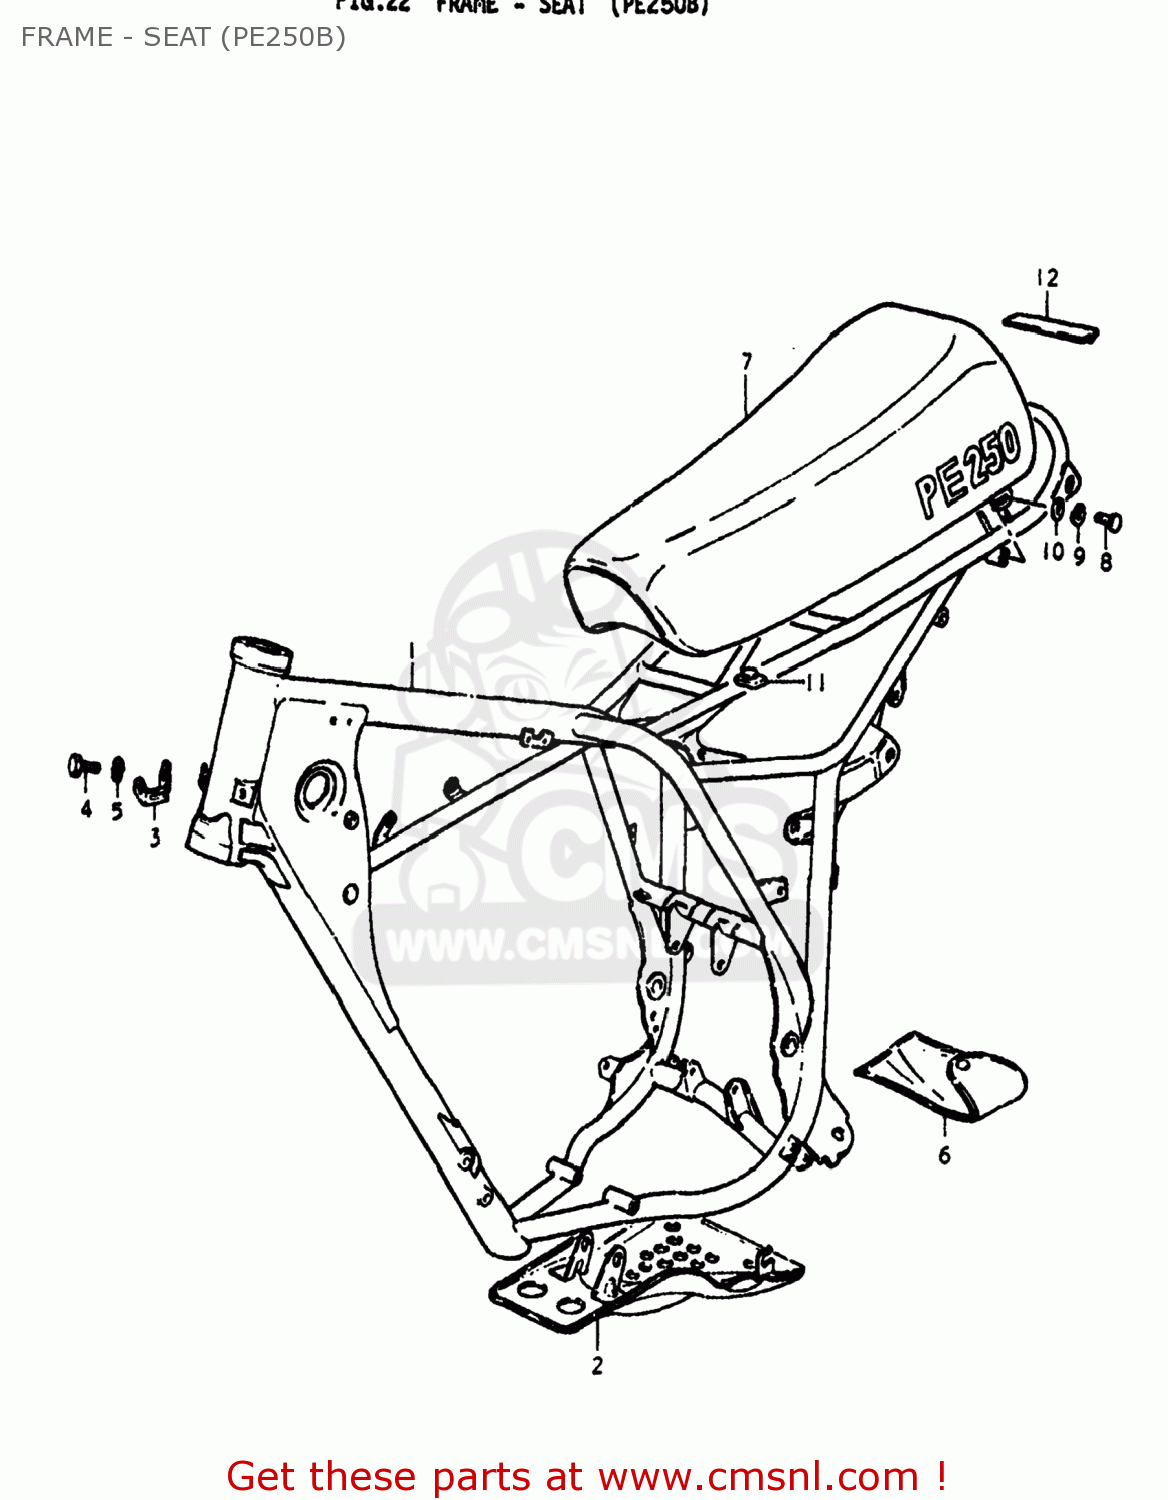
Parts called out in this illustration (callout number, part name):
1	FRAME
2	GROMMET
3	PLATE,ENGINE MOUNTING
4	BOLT
5	LOCK WASHER
7	SEAT ASSEMBLY
8	BOLT
9	LOCK WASHER
10	WASHER
11	CUSHION
12	CUSHION,FRAME
